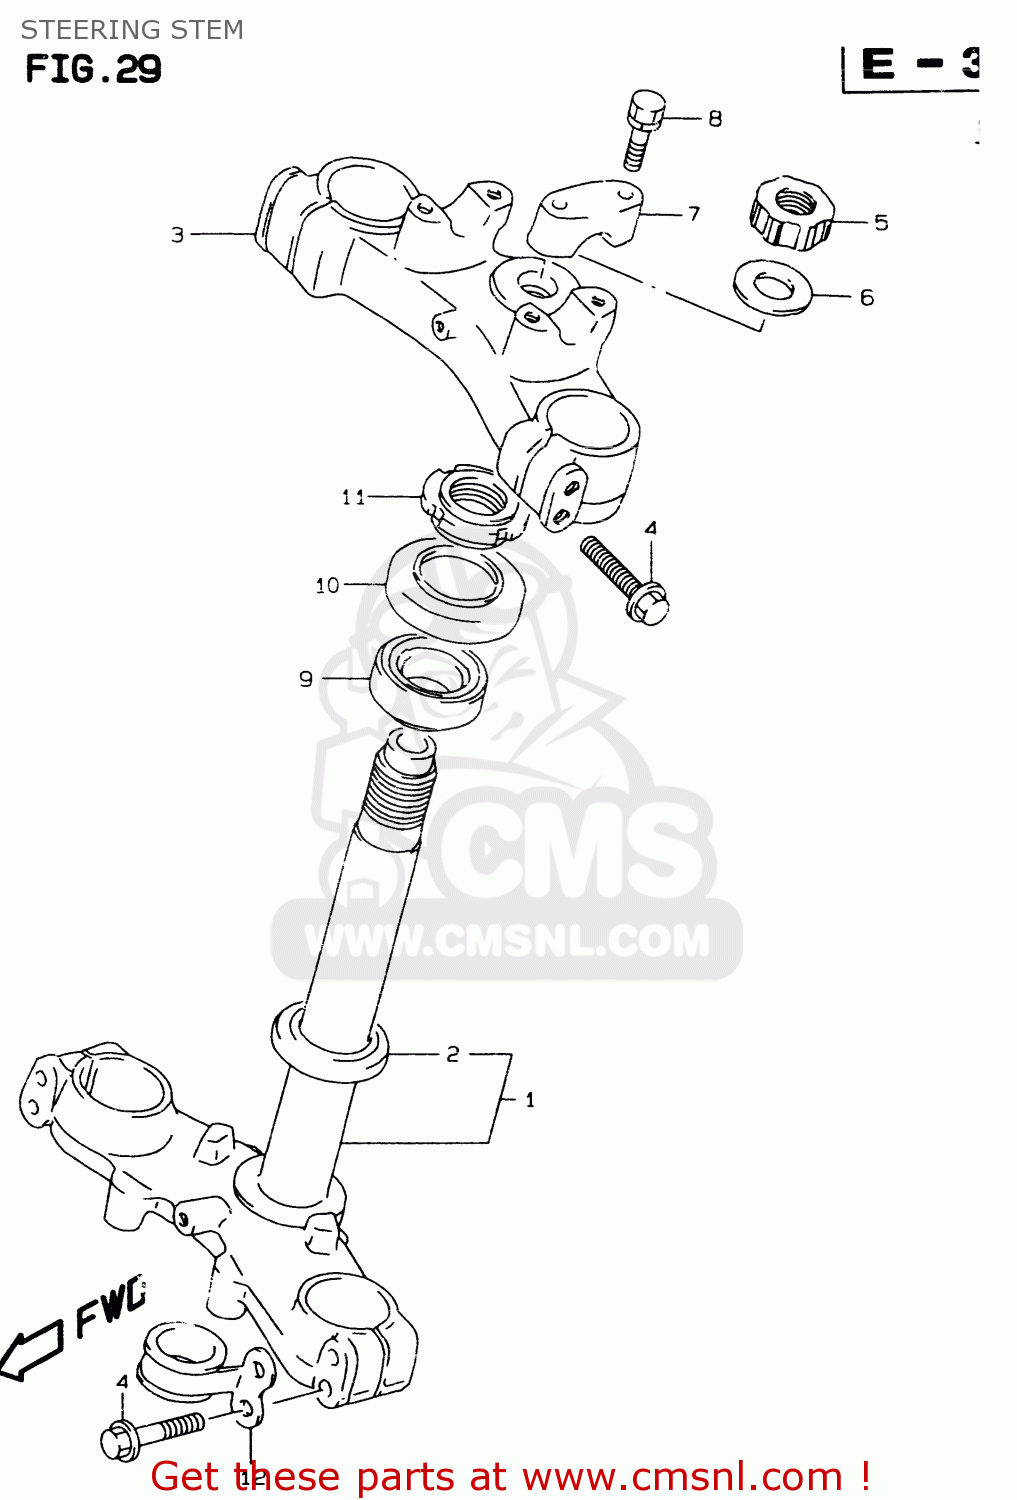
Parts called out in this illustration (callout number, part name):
1	STEM,STEERING
2	BEARING(26X47X15)
3	HEAD,STEERING STEM
4	BOLT
5	NUT
6	WASHER
7	HOLDER,HANDLEBAR
8	BOLT
9	TAPER,ROLLER BEARING
10	SEAL,STEERING UPR DUST
11	NUT,STEERING
12	CLIP
